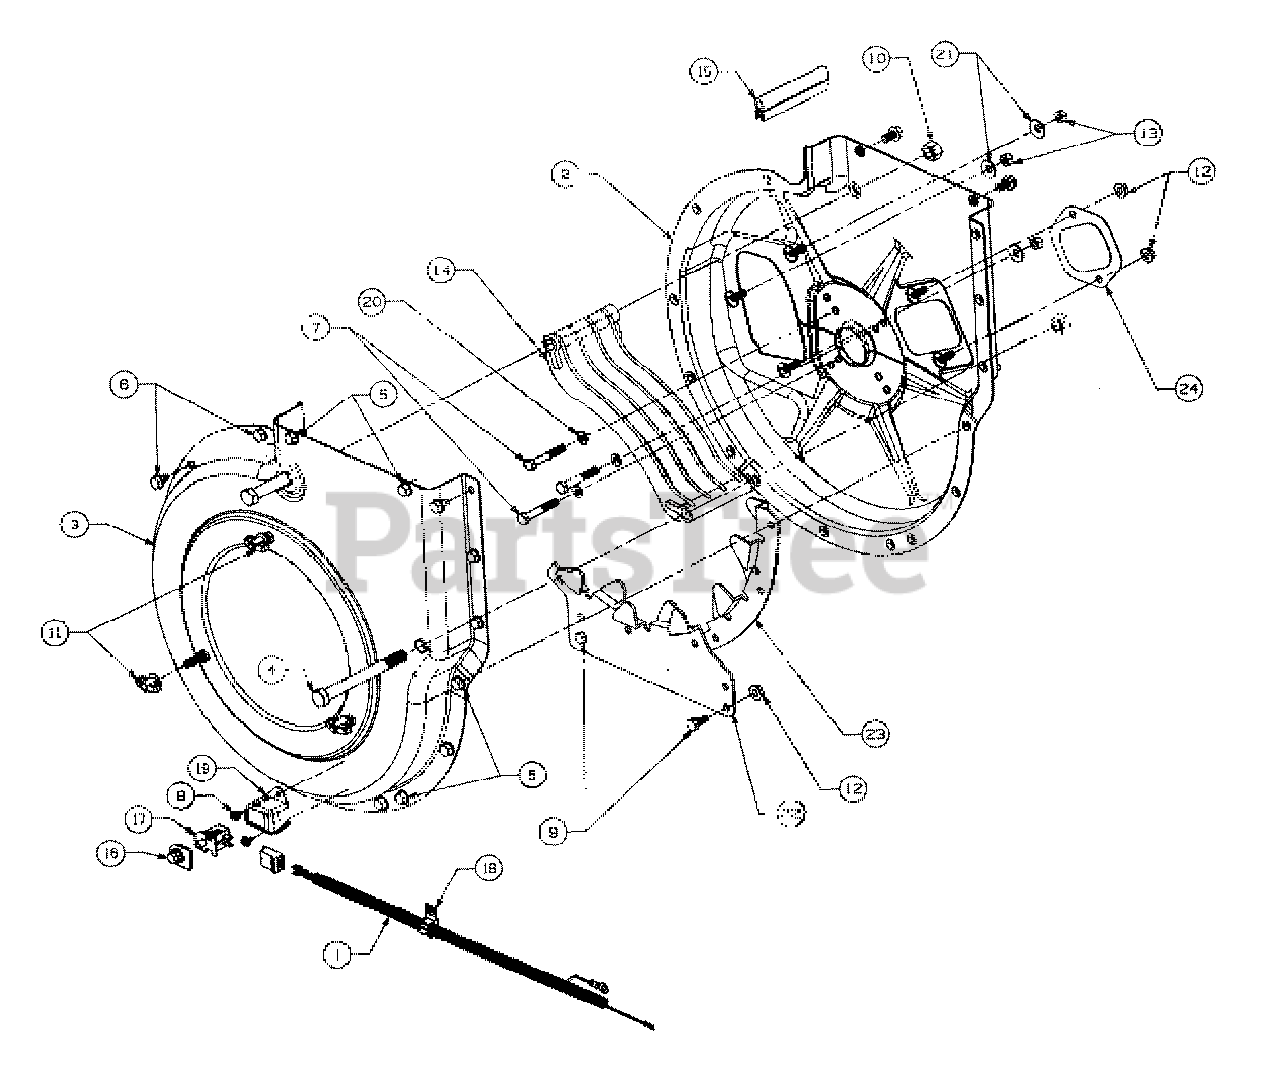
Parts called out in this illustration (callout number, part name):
1	HARNESS-CHIPPER VAC
4	SCREW-HEX
5	SCREW-HEX SELF TAP
6	SCREW-HEX SELF TAP
7	SCREW-HEX
8	SCREW-HEX SELF TAP
9	SCREW-HEX
10	NUT-HEX LOCK
12	NUT-HEX LOCK
13	NUT-HEX (GR 5)
14	SCREEN
15	SEAL-RUBBER
16	COVER-SWITCH
17	SWITCH
18	CLAMP
19	COVER SWITCH
20	WASHER-LOCK
21	WASHER-BELL
22	BLADE-FLAIL HOUSING
23	BLADE-FLAIL HOUSING
